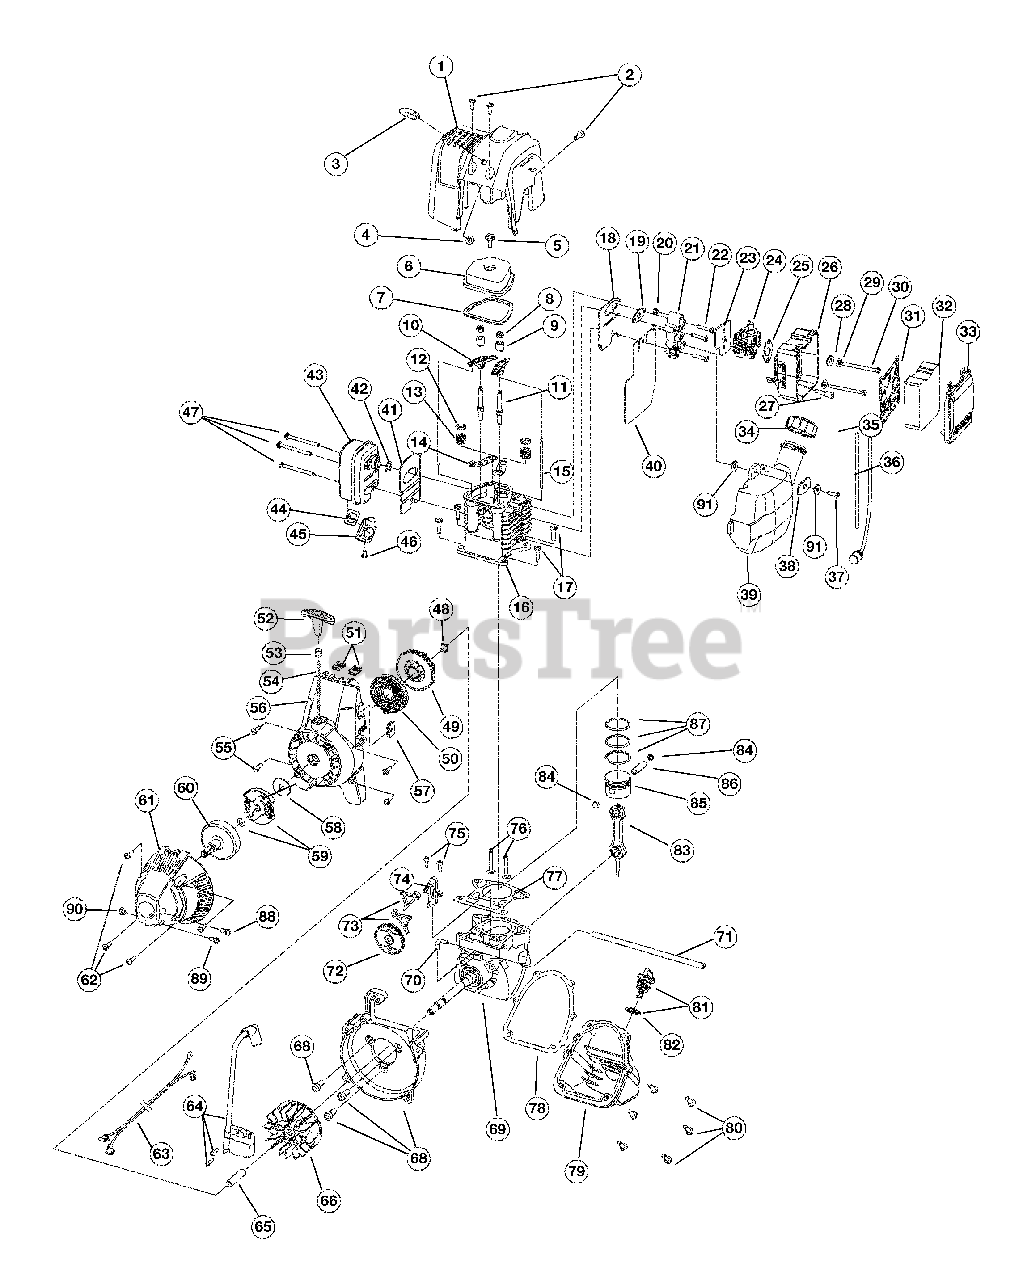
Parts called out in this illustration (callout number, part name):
1	Engine Cover
2	Engine Cover Screws
3	Starter Rope Eyelet
5	Valve Cover Screw
6	Valve Cover
7	Valve Cover Gasket
8	Rocker Adjustment Nut
9	Rocker Arm Pivot
11	Rocker Arm Stud
12	Valve Spring Retainer
13	Valve Spring
14	Push Rod Guide
15	Push Rod
16	Cylinder Assembly
17	Cylinder Screw
18	Intake Baffle
19	Carburetor Mount Gasket
20	Nut
21	Carburetor Mount
22	Carburetor Mount Screw
23	Carburetor Gasket
24	Carburetor with Primer
25	Air Filter Gasket
26	Air Filter Cover Assembly
27	Breather Tube Assembly
28	Grommet Washer
30	Air Filter Mounting Screw
31	Air Filter Plate
33	Air Filter Cover
35	Fuel Return Line
36	Fuel Pick-Up Line with Filter
38	Bushing
39	Fuel Tank Assembly
40	Fuel Tank Shield
41	Muffler Baffle
42	Muffler Gasket
43	Muffler
44	Spark Arrestor Screen
45	Screen Cover
47	Muffler Mounting Screw
49	Recoil Pulley
50	Recoil Spring
52	Pull Handle
55	Starter Housing Screw
56	Starter Housing Assembly
57	Wire Grommet
58	Clutch Washer
59	Clutch with Washer
60	Clutch Drum
61	Clutch Cover
62	Clutch Cover Screw
64	Ignition Module with Screws
66	Flywheel
68	Shroud Assembly with Screws
69	Crankcase Assembly
71	Breather Hose
73	Cam Follower
74	Cam Bracket
75	Cam Bracket Screw
76	Valves, Intake and Exhaust
77	Cylinder Gasket
78	Oil Pan Gasket
79	Oil Pan
80	Oil Pan Screw
81	Dipstick Assembly
83	Connecting Rod
84	Wrist Pin Button
85	Piston
87	Piston Ring Set
88	Anit-Rotation Screw
89	Screw
